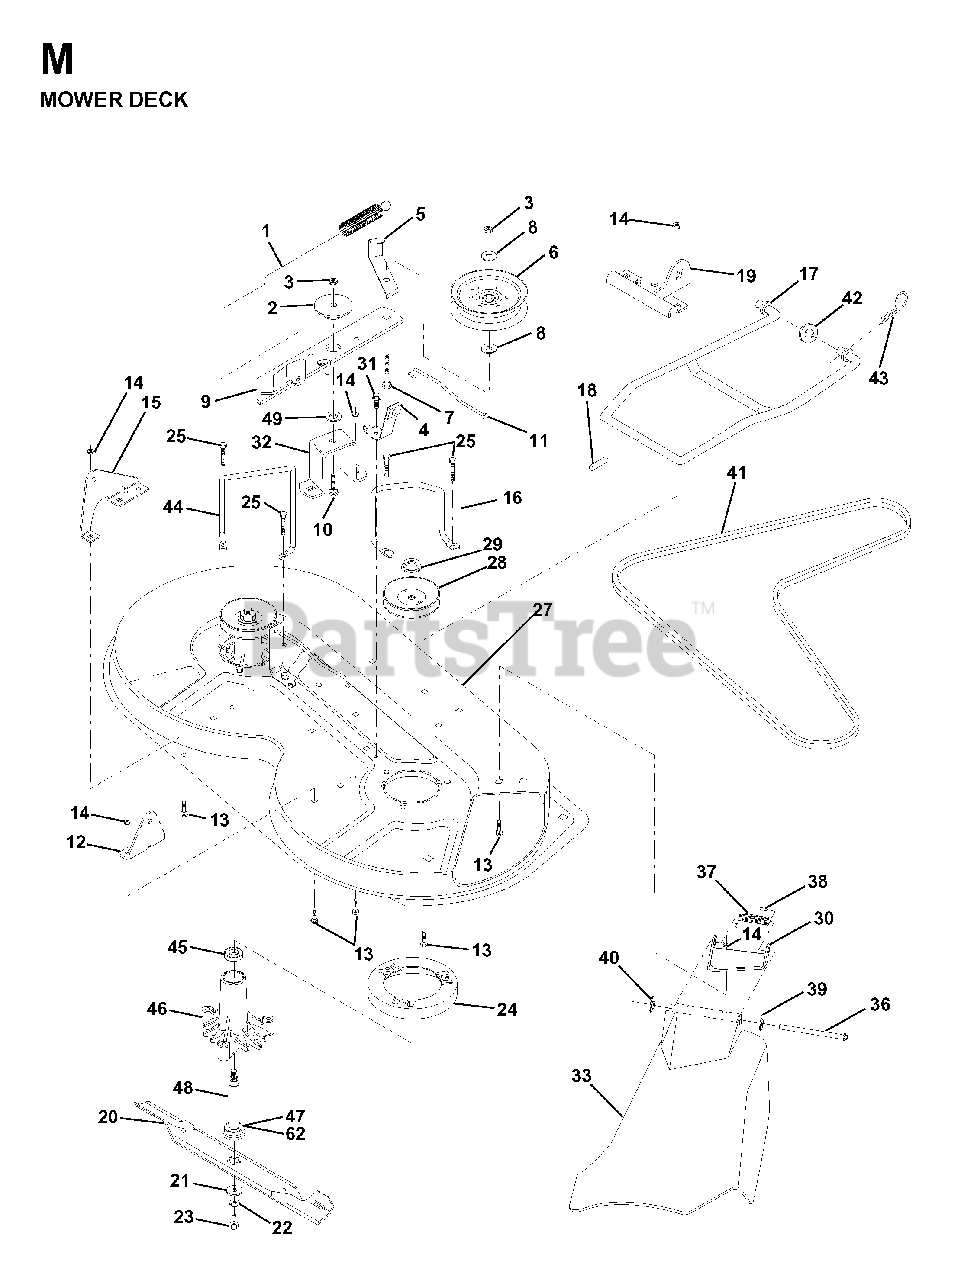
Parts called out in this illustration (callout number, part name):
1	SPRING-MOWER CLUTCH
2	SPACER RETAINER
3	LOCKNUT
4	BRAKE ASSEMBLY
5	IDLER BELT GUIDE
6	PULLEY IDLER
7	BOLT
8	WASHER
9	IDLER ARM ASSY
10	BOLT.3/8-14X1.25
11	BRAKE ROD
12	BRKT LIFT REAR
13	BOLT
14	LOCKNUT
15	BRKT LIFT REAR LH
16	BELT KEEPER
17	MOWER LINK STABILIZER
18	PIN GROOVE
19	BRKT LINK STABILIIZER
20	BLADE, HI-LIFT 36" PREMIUM
21	WASHER.BLADE
22	LOCKWASHER
23	BLADE BOLT
24	STRIPPER
25	SCREW THDROL ROLLING WASHER HD
27	MOWER HOUSING
28	PULLEY, MANDREL
29	NUT
30	BRACKET ASM DEFLECTOR
32	SUPT,IDLER ARM
33	DEFLECTOR
36	HINGE ROD
37	SPRING TORSION
38	CAP-SLEEVE LT
39	WASHER
40	NUT PUSH M
42	WASHER
43	SPRING RETAINER
44	KEEPER LH
46	HSG MANDREL
47	BEARING
48	SHAFT ASM VENT
49	HARDENED WASHER
62	WASHER FELT
